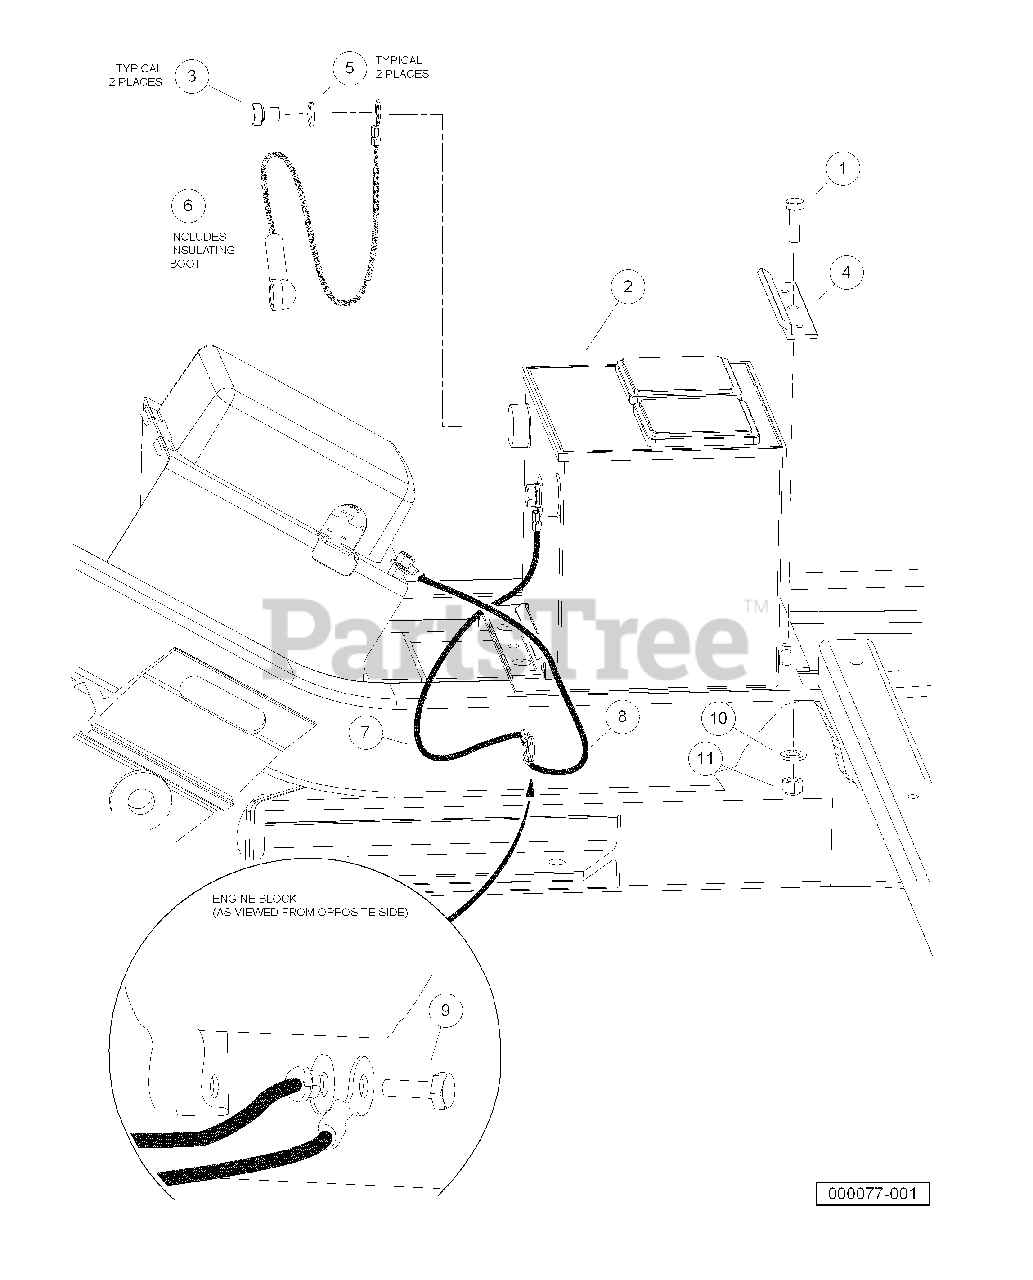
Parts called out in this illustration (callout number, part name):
1	Screw, 5/16-18 X 1.00 Hex Cap
2	Battery, 12-Volt
3	Screw, 3/8-16 X 0.50 Stainless Steel Hex-Head
4	Clamp, Battery
5	Lockwasher, 3/8 Stainless Stl
6	Asm, #6 Red Wire
7	Asm, #6 Blk Wire
8	Asm, #6 Blk Wire
9	Bolt, M6 X 1 X 16 Loctite
10	Washer, 5/16 Type A Flat
11	Locknut, 5/16-18 Nylon Insert
